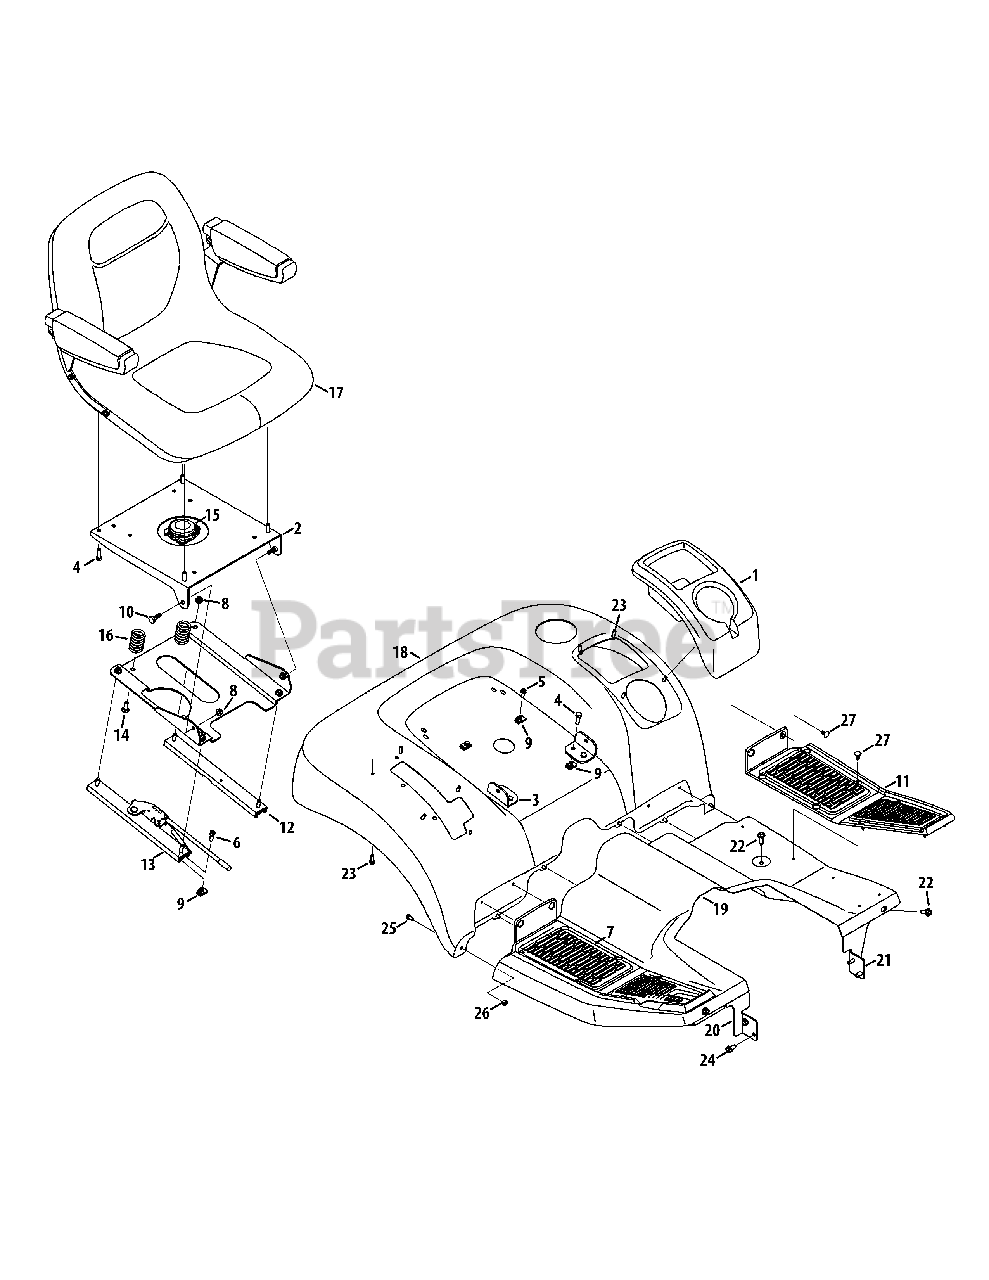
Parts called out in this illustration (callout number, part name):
1	LH Cup/Compartment Cover
2	Seat Mount Plate
3	Suspension Seat Front Pivot Bracket
4	Hex Screw, 5/16-18 x 1.00
5	Hex Flange Screw, 5/16-18
6	Socket Screw, 5/16-18 x .750
7	RH Floor Pad
8	Flange Lock Nut, 5/16-18
9	U-Nut, 5/16-18
10	Shoulder Screw, 5/16-18 x .437 x .268
11	LH Floor Pad
12	Seat Track w/o Latch
13	Seat Track w/ Latch
14	Carriage Screw, 5/16-18 x 1.00
15	Seat Switch, 1/4
16	Compression Spring
18	Fender
19	Running Board
20	RH Running Board Bracket
21	LH Running Board Bracket
22	Hex Washer Screw, 5/16-18 x 1.000
23	Hex Washer Screw, 1/4-15 x .750
24	Hex Washer Screw, 5/16-18 x .750
25	Hex Screw, 1/4-20 x .50
26	Hex Lock Nut, 1/4-20
27	Ratchet Clip, .250
